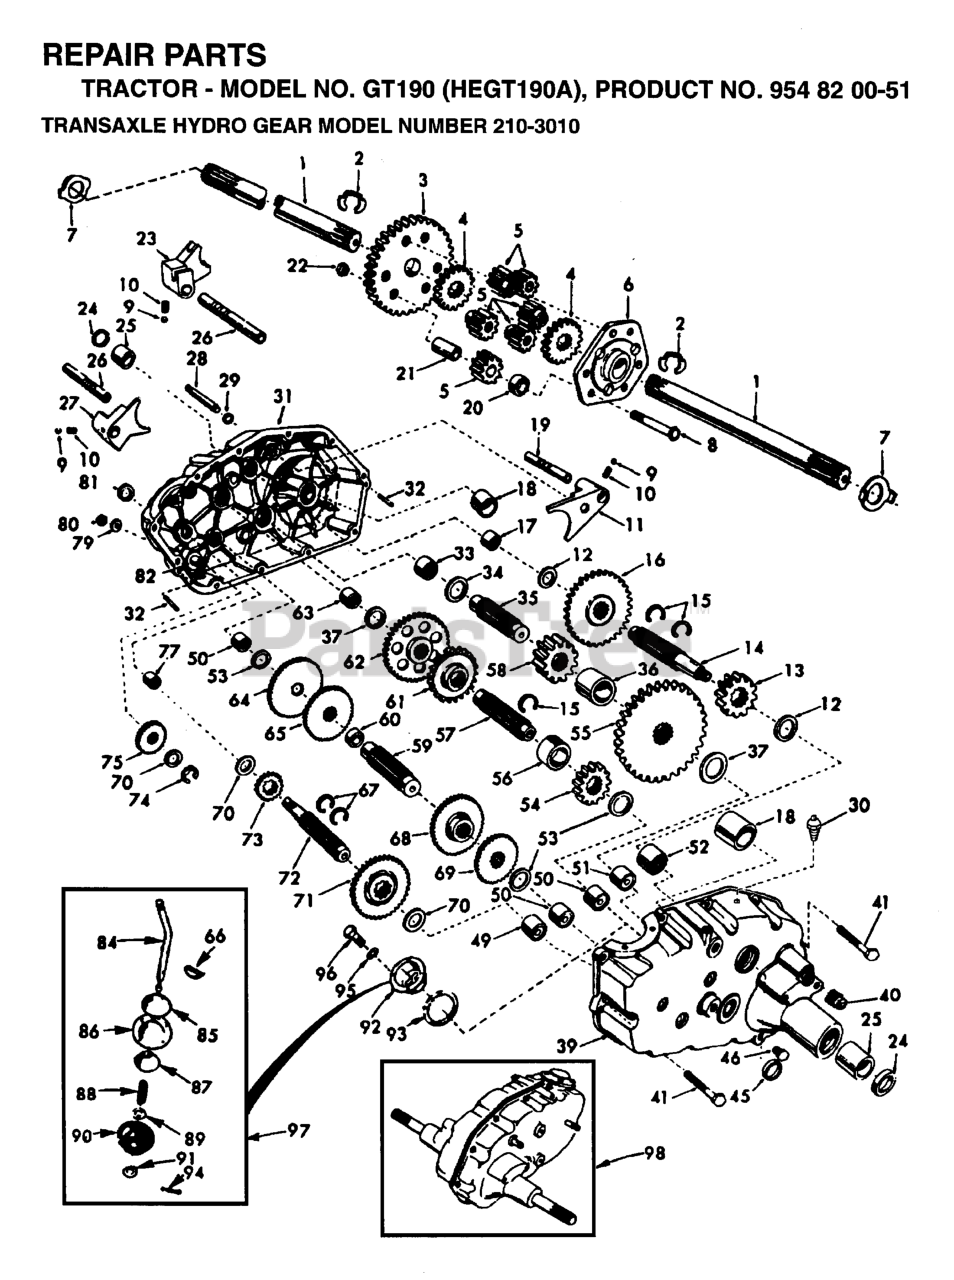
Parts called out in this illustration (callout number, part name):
1	AXLE SHAFT T
2	Ring, Klip Truarc #5304-75
3	FINAL GEAR T
4	DIFF GEAR T
5	DIFF PINION T
6	DIFF CARRIER T
7	WASHER T
8	Bolt, Hex Head 3/8-24 x 3-1/4 (1" Thread Length)
9	STEEL BALL KIT
10	SPRING
12	THRUST WASHER
13	RED PINION T
14	GEAR SHAFT
15	SNAP RING T
16	GEAR T
18	BEARING
21	PINION RS
22	GRIPCO NUT
24	OIL SEAL STD
25	BRNG. T
26	SHAFT SHIFT FORK
27	SHIFT FORK T
28	SHIFT SHAFT
29	SEAL.OIL.SHAFT.SHIFT.T
31	GEARCASE.RH.W/BEARING
33	NEEDLE BRNG T
34	WASHER RACE BEARING THRUST
35	GEAR SHAFT T
36	GEAR SPACER T
39	GEARCASE LH
40	Pipe Plug 1/2-14 N.P.T.
41	BOLT.5/16-18X1.25
49	BEARING TI
50	NEEDLE BRNG T
51	NEEDLE BRNG T
52	BEARING STD
53	BRNG RACE T
54	RED PINION T
55	RED GEAR T
56	PINION SPACER T
57	GEAR SHAFT T
58	FINAL PINION T
59	GEAR SHAFT T
61	RED PINION T
62	RED GEAR T
64	LOW SPEED GEAR T
65	GEAR.REVERSE.T
67	Snap Ring, Crescent Type
68	GEAR.SPEED.INTERMEDIATE.T/A
69	HIGH SPEED GEAR T
70	THRUST WASHER
71	CLUSTER GEAR T
72	SHAFT
73	LO SPEED PINION T
75	IDLER GEAR T
77	NEEDLE BEARING TI
80	NUT **
81	SEAL STD
82	SHAFT REVERSE IDL
84	GEAR SHIFT LVR T
86	COVER AND PIN T
87	GUIDE BALL T
90	SEAL.SHIFT
91	Washer 9/16 x 15/16 x 12 Gauge
92	GEAR SHIFT GATE T
94	COTTER PIN
95	WASHER.LOCK.HVY.HLCL.SPR.5/16
96	BOLT
97	GEAR SHFT LVR T
98	TRANSAXLE ASSY
